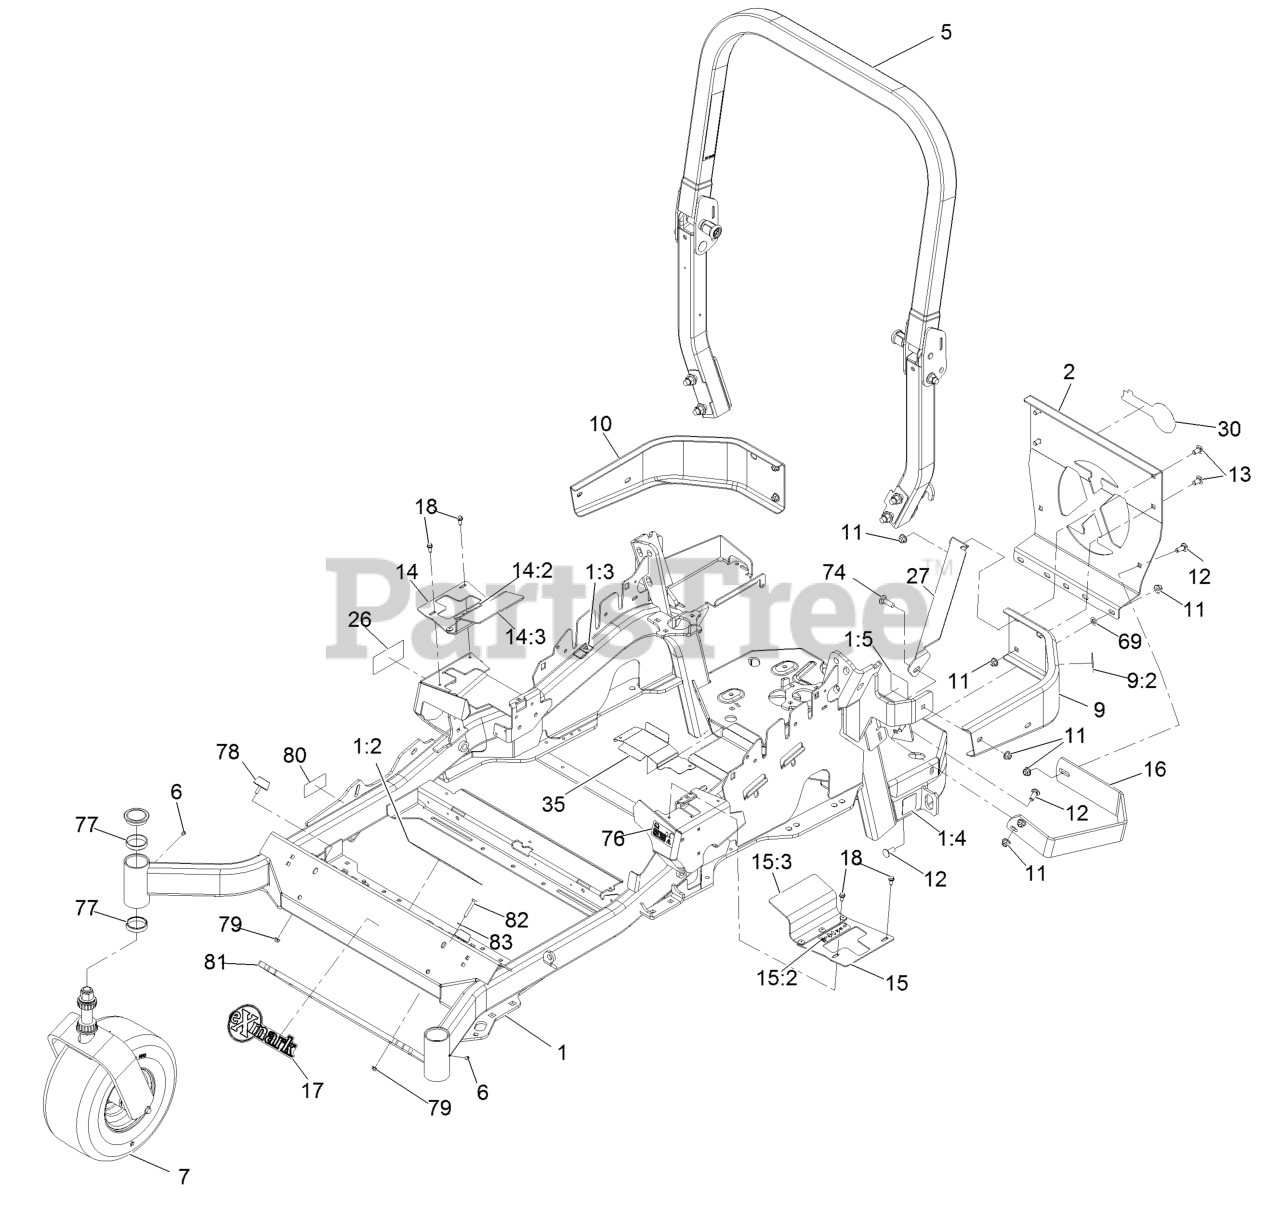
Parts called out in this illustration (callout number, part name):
1	MAINFRAME ASM
1:2	DECAL-DANGER
1:3	DECAL-WARNING
1:4	DECAL-HAZARD, PINCHED FINGER
1:5	DECAL-SPARK ARRESTER
2	PLATE,REAR GUARD
5	ROPS ASM
7	Front Caster And Fork ASM
9	LH BUMPER ASM
9:2	DECAL-WARNING
10	BUMPER-RH
11	NUT-HF, NI
12	SCREW-CARR
13	SCREW-CARR
14	RH MOTION CONTROL COVER A
14:2	DECAL-CONTROL, MOTION
14:3	FLAP-RUBBER
15	LH MOTION CONTROL COVER A
15:2	DECAL-CONTROL, MOTION
15:3	FLAP-RUBBER
16	GUARD-MUFFLER
17	DECAL-EXMARK LOGO
18	SCREW-HWH
26	DECAL-E-SERIES
30	DECAL-EXMARK LOGO
35	GUARD-BELT
69	NUT-PUSH
74	BOLT-CARR
76	DECAL-FUEL FILL, CE
77	CUP-BEARING
80	Decal-Patent
81	WEIGHT-TOE BOARD
82	SCREW-HH
83	WASHER-FLAT
